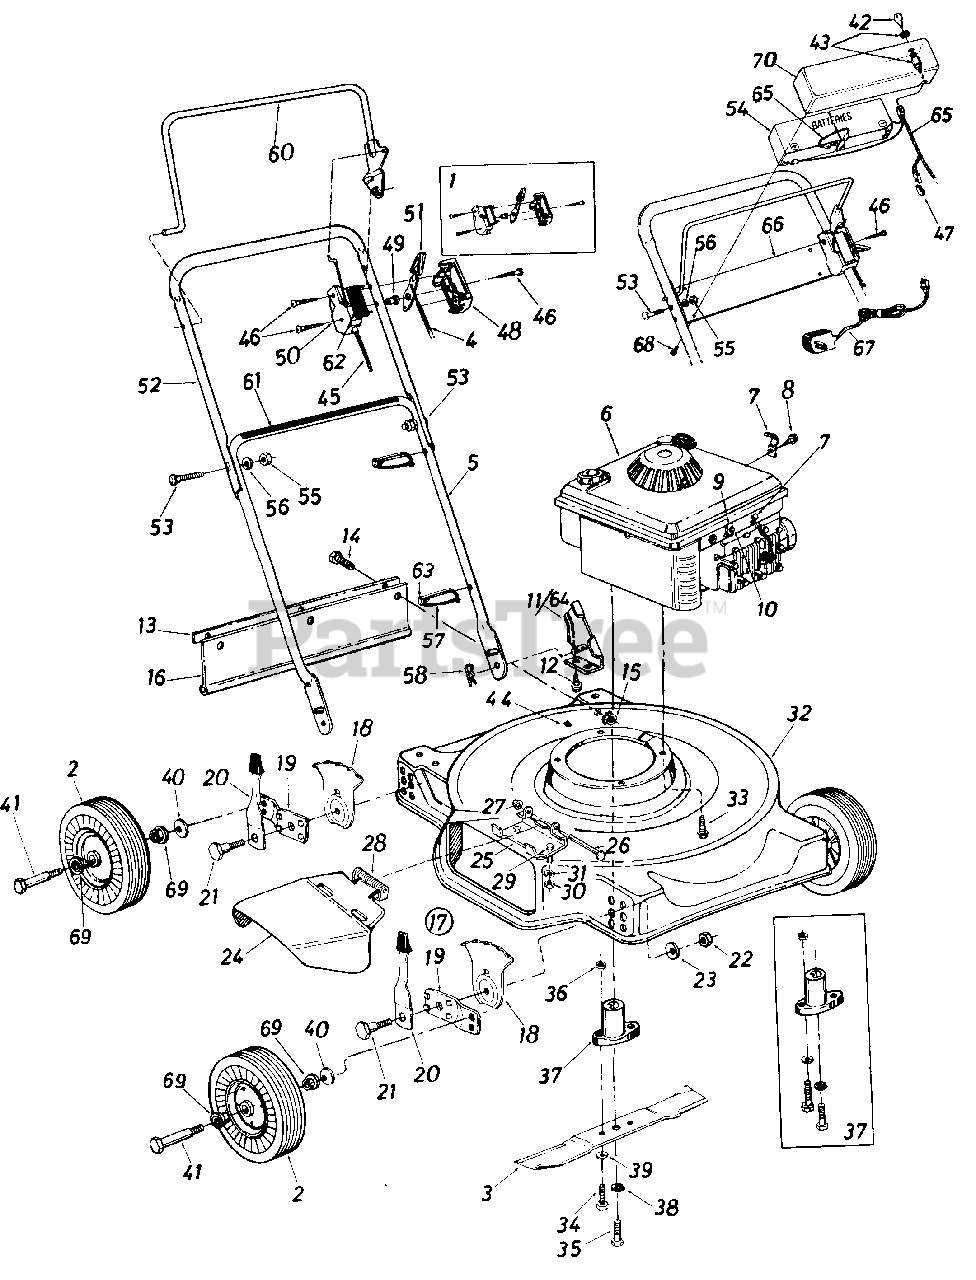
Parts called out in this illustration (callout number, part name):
1	Kit-Control Housing Comp.
2	Wheel Ass'y.
3	Blade-20"
4	Throttle Control Wire-53"
5	Lower Handle
6	Engine
7	Casing Clamp
8	Hex B-Tap Scr. #10 x .38"
9	Casing Clamp
10	Hex AB-Tap Scr. #10 x .62" Lg.
11	Handle Mount Brkt.-L.H.
12	Hex Wash. Hd. B-Tap Scr. 5/16-18 x .50" Lg.
13	Retaining Strip
14	Hex Bolt 1/4-20 x .62" Lg.*
15	Hex Sems Nut 1/4-20 Thd.*
16	Rear Flap Ass'y.
17	Height Adj. Ass'y.-R.H.
18	Height Adj. Plate
19	Pivot Bar
20	Spring Lever w/Knob
21	Shld. Bolt .500" Dia. x .375
22	Hex Nut 3/8-16 Thd.*
23	Bell-Wash. .39" I.D. x 1.13" O.D.
24	Chute Deflector Ass'y.-Comp.
25	Deflector Hinge Plate
26	Pivot Pin
27	Cap Speed Nut 1/4" Rod
28	Torsion Spring
29	Hex Bolt 1/4-20 x .50" Lg.*
30	Hex Nut 1/4-20 Thd. *
31	L-Wash. 1/4" I.D.*
34	Hex Bolt 5/16-24 x 1.00" Lg. (Grade 8)
35	Hex Bolt 3/8-24 x 2.25" Lg. (Grade 5)
36	Hex Nut 5/16-24 Thd.*
37	Blade Adapter Kit
38	L-Wash. 3/8" I.D. Heavy Duty
39	L-Wash. 5/16" I.D.
40	Bell-Wash. .400" I.D. x .88" O.D.
41	Shld. Bolt .498" Dia. x 1.450" Lg.
42	Ignition Key
43	Ignition Switch
45	Control Cable-39"
46	Truss. Mach. Scr. #12 x 1.50" Lg.
47	Plug
48	Control Panel Half
49	Control Disc Pin
50	Clutch Panel Half
51	Throttle Control Lever
52	Upper Handle
53	Curved Carriage Bolt 5/16-18 x 1.38" Lg.
54	Battery Pack
55	Hex Nut 5/16-18 Thd.
56	L-Wash. 5/16" I.D.
57	Cable Tie
58	Internal Cotter Pin
60	Control Handle-L.H.
61	Instruction Label-Handle
62	Control Label-Throttle
63	Cable Anchor
65	Wire Harness
66	Lower Battery Tray
67	Battery Charger
68	Truss Mach. Hi-Riser Tap Scr. 1" Lg.
69	Ball Bearing
70	Battery Tray
